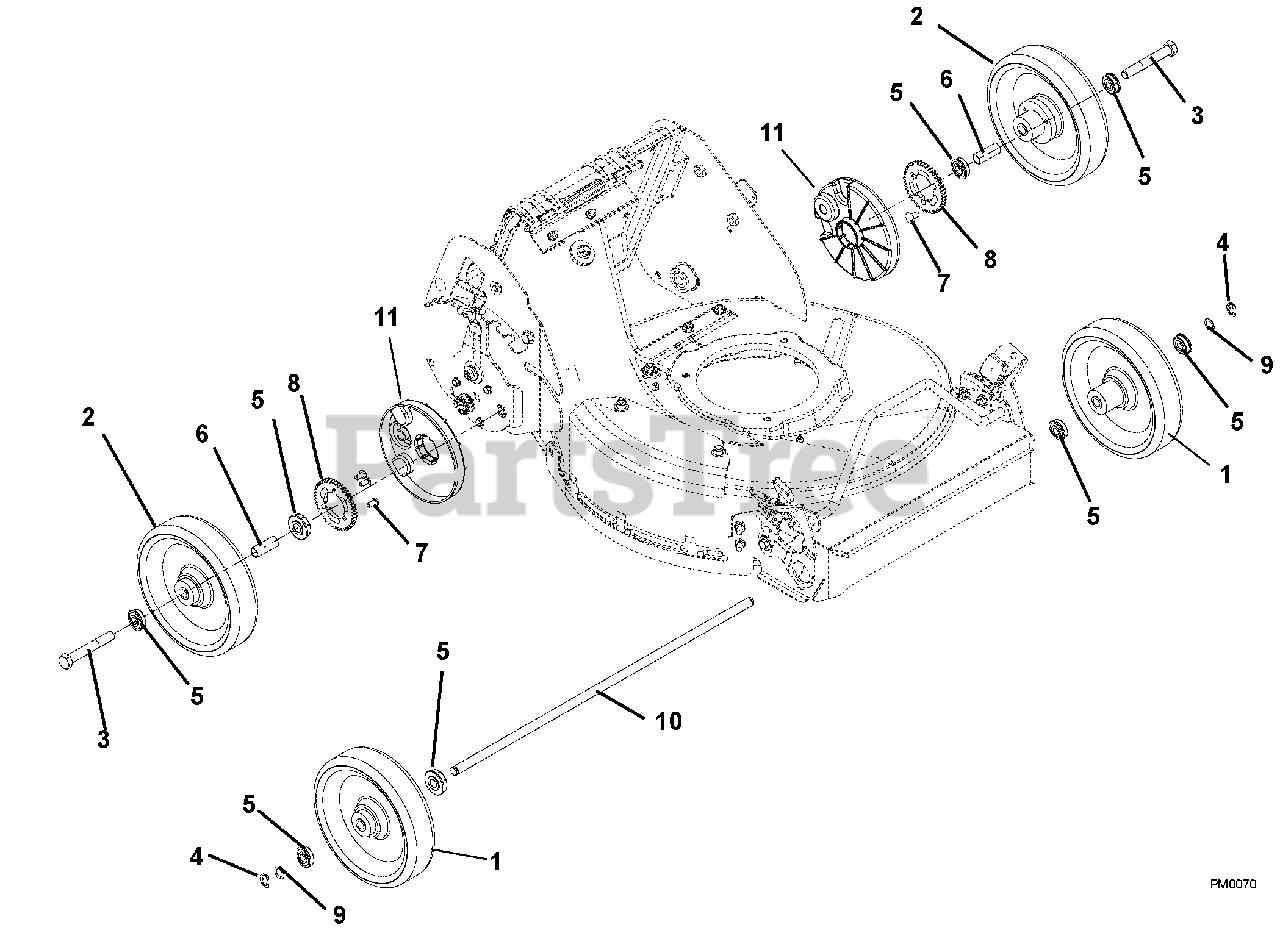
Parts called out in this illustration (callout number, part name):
1	Tire, 8 x 1.75 Commercial Front (Includes item 5)
2	Tire, 8 x 1.75 Commercial Rear (Includes items 5 and 6)
3	Bolt, Hex .50-13 x 3.50 Grade 8
4	Ring, Retaining-External .500 x .042
5	Bearing, Ball .50 x 1.38 x .438 Sealed
6	Spacer, Wheel
7	Screw, Tapping 1/4-20 x 3/4
8	Gear, Wheel
9	Washer, .500 x .750 x .020 Thrust
10	Axle Shaft
11	Cover, Wheel
